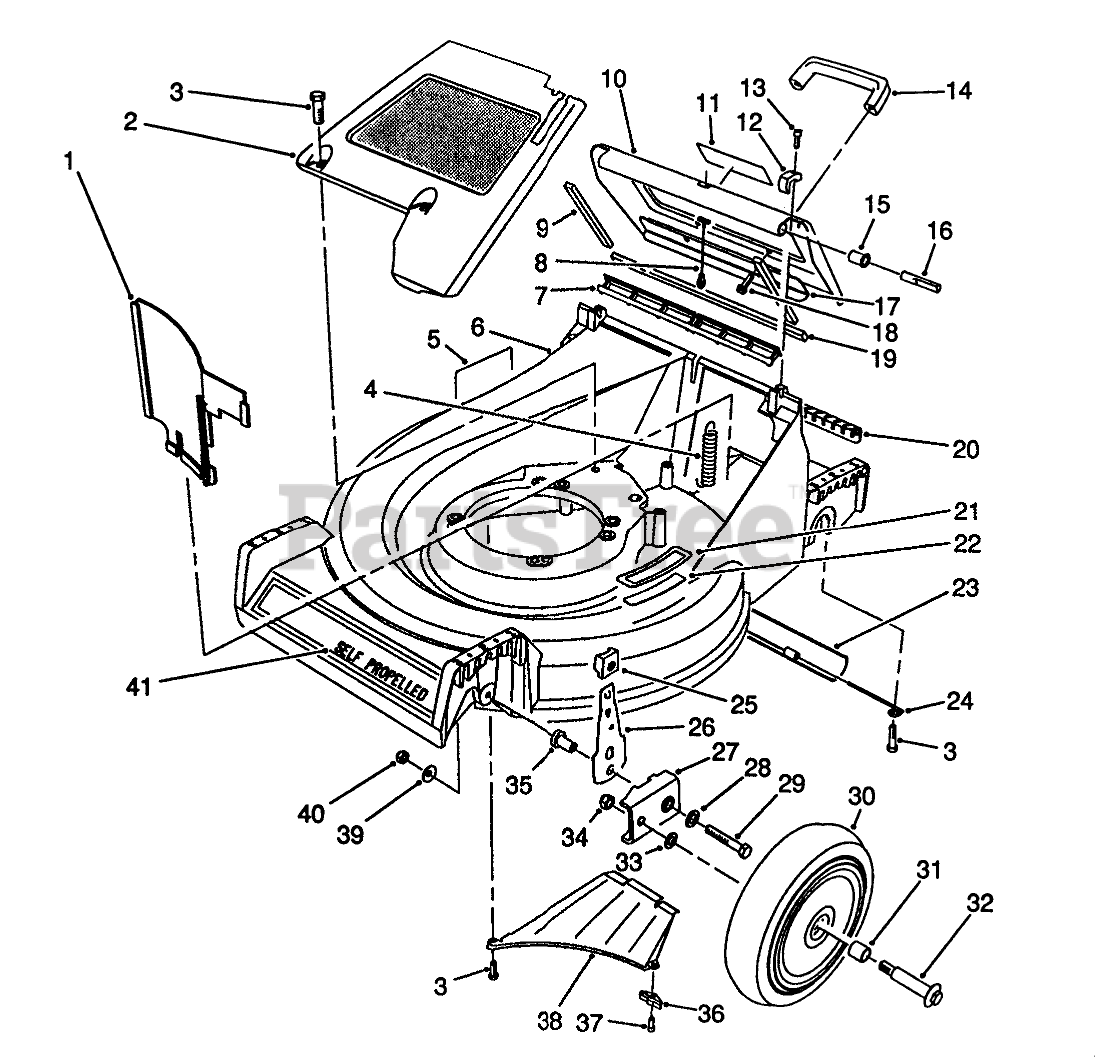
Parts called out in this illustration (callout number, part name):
1	PANEL-VERTICAL
2	PaneI-Screen
3	SCREW-HWHTF
4	EXTENSION-SPRING
5	DECAL-DANGER
6	21" Housing Assembly (Incl. Ref. #5, 21-22 & 41)
7	DOOR SEAL
8	DOOR CABLE
9	DOOR SIDE SEAL
10	Door-Discharge (Incl. Ref. #9, 11, 17 & 19)
11	DECAL - WARNING
12	HINGE CLAMP
13	SCREW-HSH
14	HANDLE-DOOR
15	DOOR BUSHING
16	HINGE PIN
17	DOOR - BRACE
18	SCREW-HWH
19	DOOR END SEAL
20	ACCESS COVER
21	STEP PAD
22	STEP PAD DECAL
23	TRAILING SHIELD
24	LH SHIELD HANGER
25	KNOB-ARM
26	SPRING ARM ASSEMBLY
27	HP PIVOT ARM ASM
28	WASHER-FLAT
29	SCREW-HH
30	Wheel & Tire Assembly (Incl. Ref. #31)
31	BUSHING
32	WHEEL BOLT
33	WASHER
34	Nut
35	BUSHING-FLANGE
36	Bracket-Discharge
37	SCREW-HWHTF
38	Ramp Discharge
39	WASHER-BELLEVILLE
40	NUT-LOCK, NI
41	DECAL - DECK
